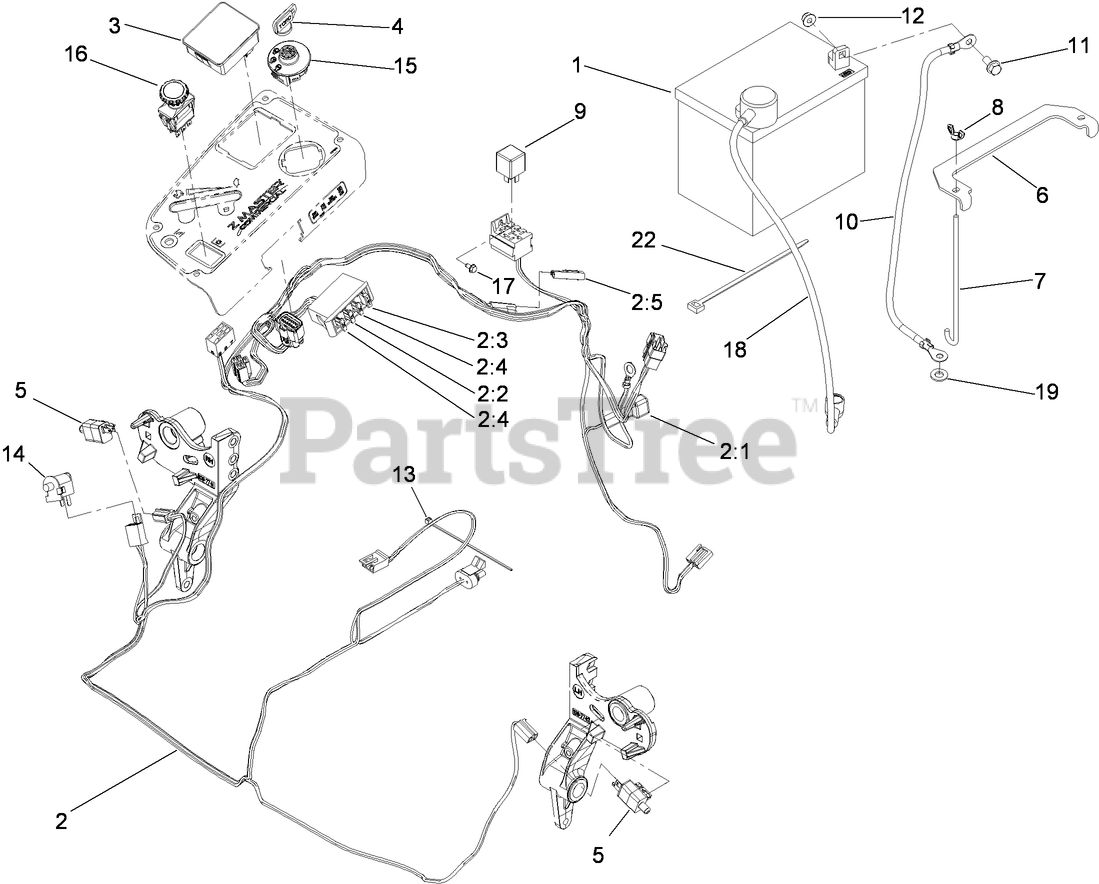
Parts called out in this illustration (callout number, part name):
1	BATTERY
2	HARNESS-WIRE, MAIN
2:2	FUSE-BLADE, 10 AMP
2:3	FUSE-BLADE, 15 AMP
2:4	FUSE-BLADE, 25 AMP
2:5	CAP-PLUG
3	MODULE-METER, HOUR
4	KEY-IGNITION
5	SWITCH
6	STRAP-TIE DOWN, BATTERY
7	BOLT-HOLDDOWN
8	WINGNUT
10	CABLE-BATTERY, NEGATIVE
11	SCREW-HHF
12	NUT-HF, NI
13	TIE-CABLE
14	SWITCH-BAIL
15	SWITCH-IGNITION
16	SWITCH-PTO, 10 AMP
17	SCREW-HWH
18	CABLE-BATTERY, POSITIVE
19	WASHER-FLAT
22	TIE-PLASTIC
